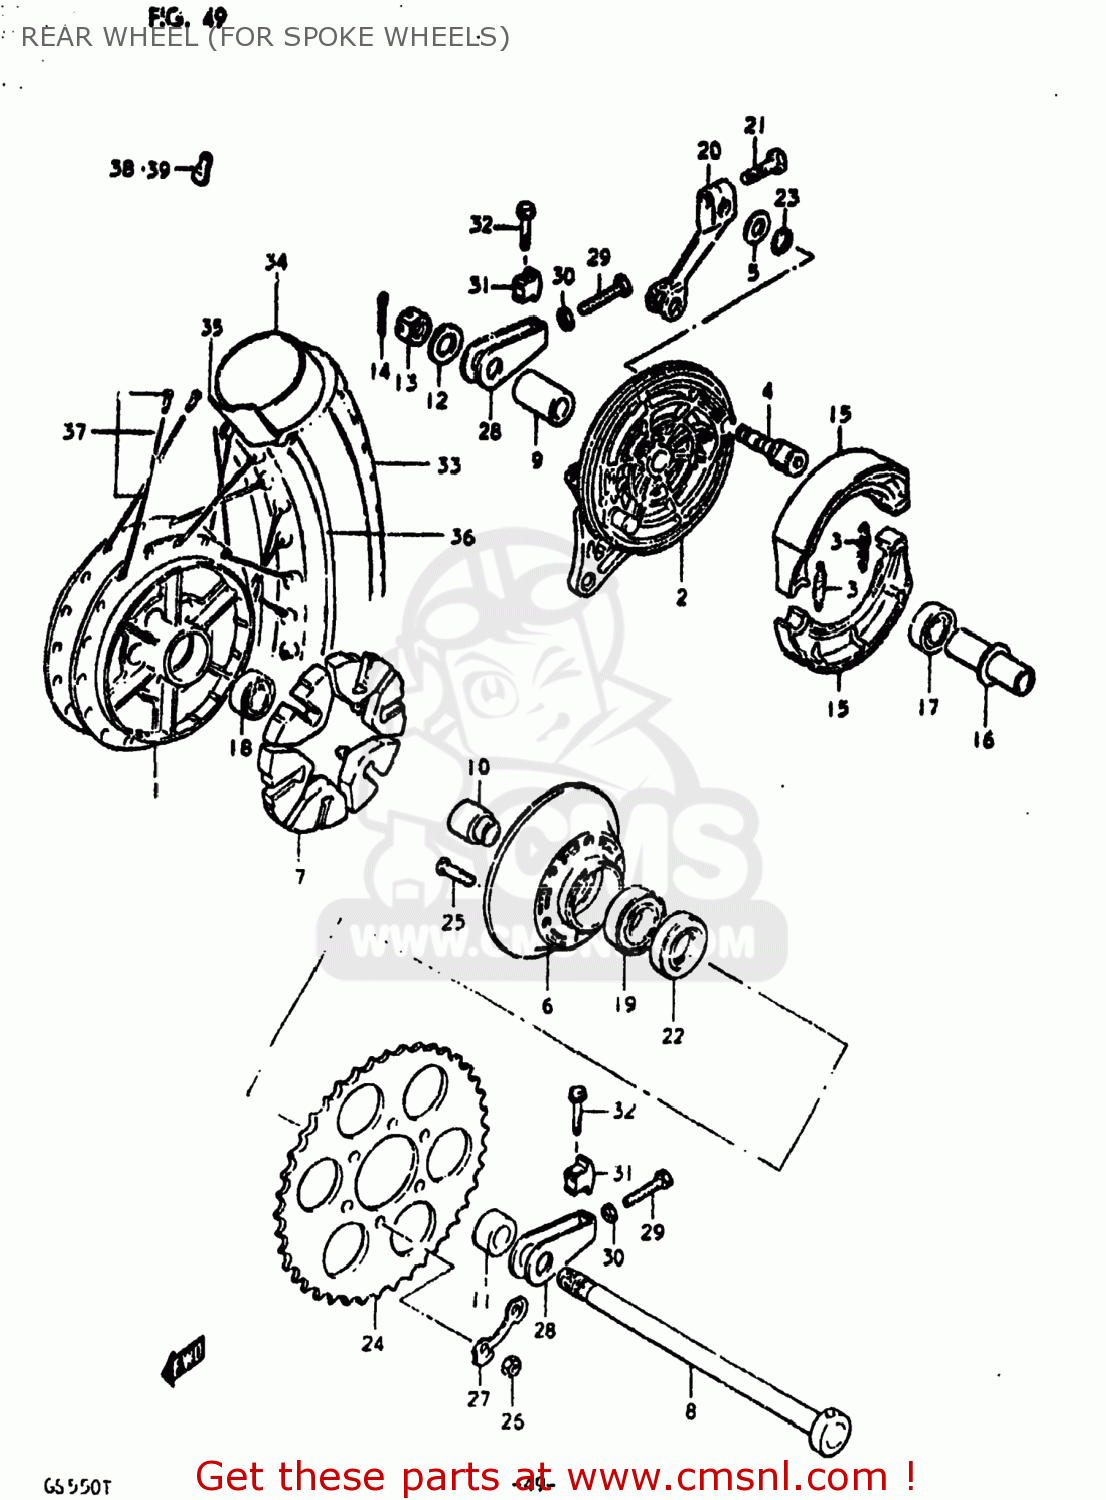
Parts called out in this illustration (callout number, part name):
1	DRUM,REAR HUB
2	PANEL,REAR HUB
3	SPRING,BRAKE SHOE
4	CAM,FRONT BRAKE
5	WASHER (15X24X1.6)
6	DRUM,REAR SPROCKET MOUNT
7	CUSHION,REAR DRUM
8	AXLE,REAR
9	SPACER(17X30.5X22.3)
10	SPACER,REAR HUB BEARING
11	SPACER (17.5X28X51.8)
12	WASHER (17X30X3.2)
13	NUT
14	PIN,COTTER
15	SHOE,BRAKE
16	SPACER
17	BEARING
18	BEARING
19	BEARING
20	LEVER,RR BRAKE CAM
21	BOLT
22	OIL SEAL
23	O-RING,BOSS
24	SPROCKET,REAR
25	BOLT
26	NUT
27	WASHER
28	ADJUSTER,CHAIN
29	BOLT
30	NUT
31	SUPPORTER,CHAIN ADJUST
32	BOLT
33	TIRE
34	TUBE,INNER
35	PROTECTOR,WHEEL,INNER
36	RIM,WHEEL
37	SPOKE SET,REAR
38	BALANCER,WHEEL (B)
39	BALANCER,WHEEL (30G)
